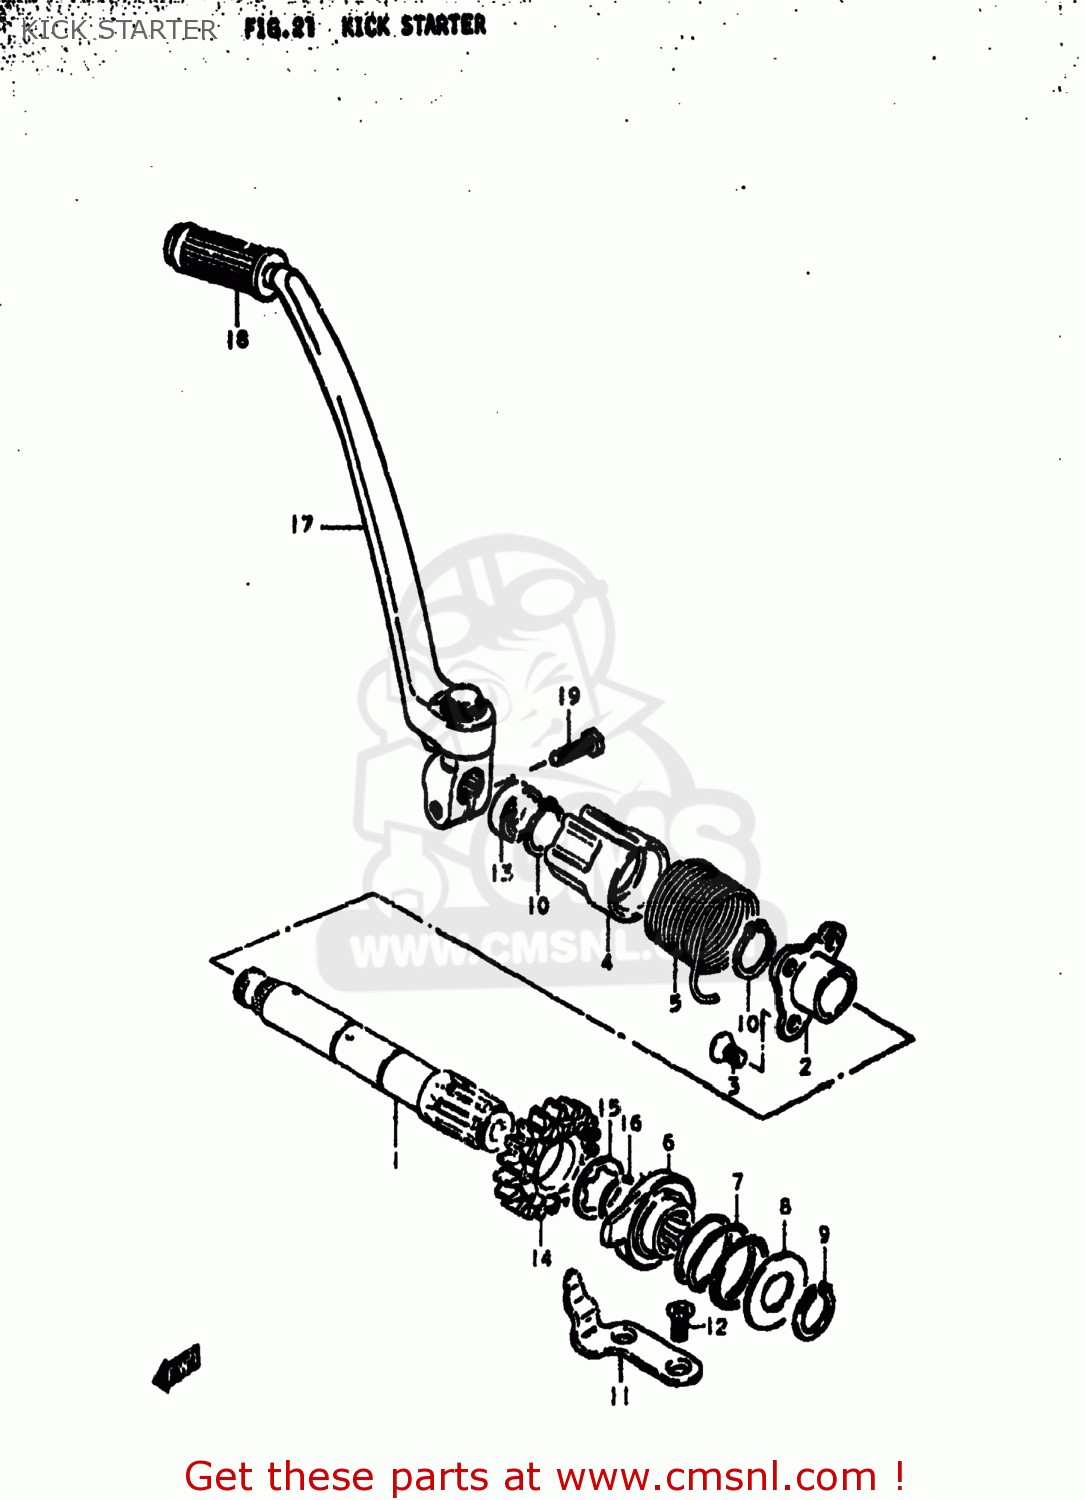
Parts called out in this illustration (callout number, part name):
1	SHAFT,KICK STARTER
2	HOLDER,KICK STARTER SHAFT
3	SCREW
4	GUIDE,STARTER SHAFT SPRING
5	SPRING
6	STARTER,KICK
7	SPRING
8	WASHER
9	SPACER (17*25*10.5)
10	CIRCLIP
11	GUIDE,STARTING SPRING
12	SCREW
13	SEAL,OIL(20X27X5)
14	GEAR,KICK STARTER DRIVE
15	WASHER,LOCK
16	CIRCLIP
17	LEVER ASSEMBLY,KICK STARTER
18	RUBBER,KICK STARTER PEDAL
19	BOLT
